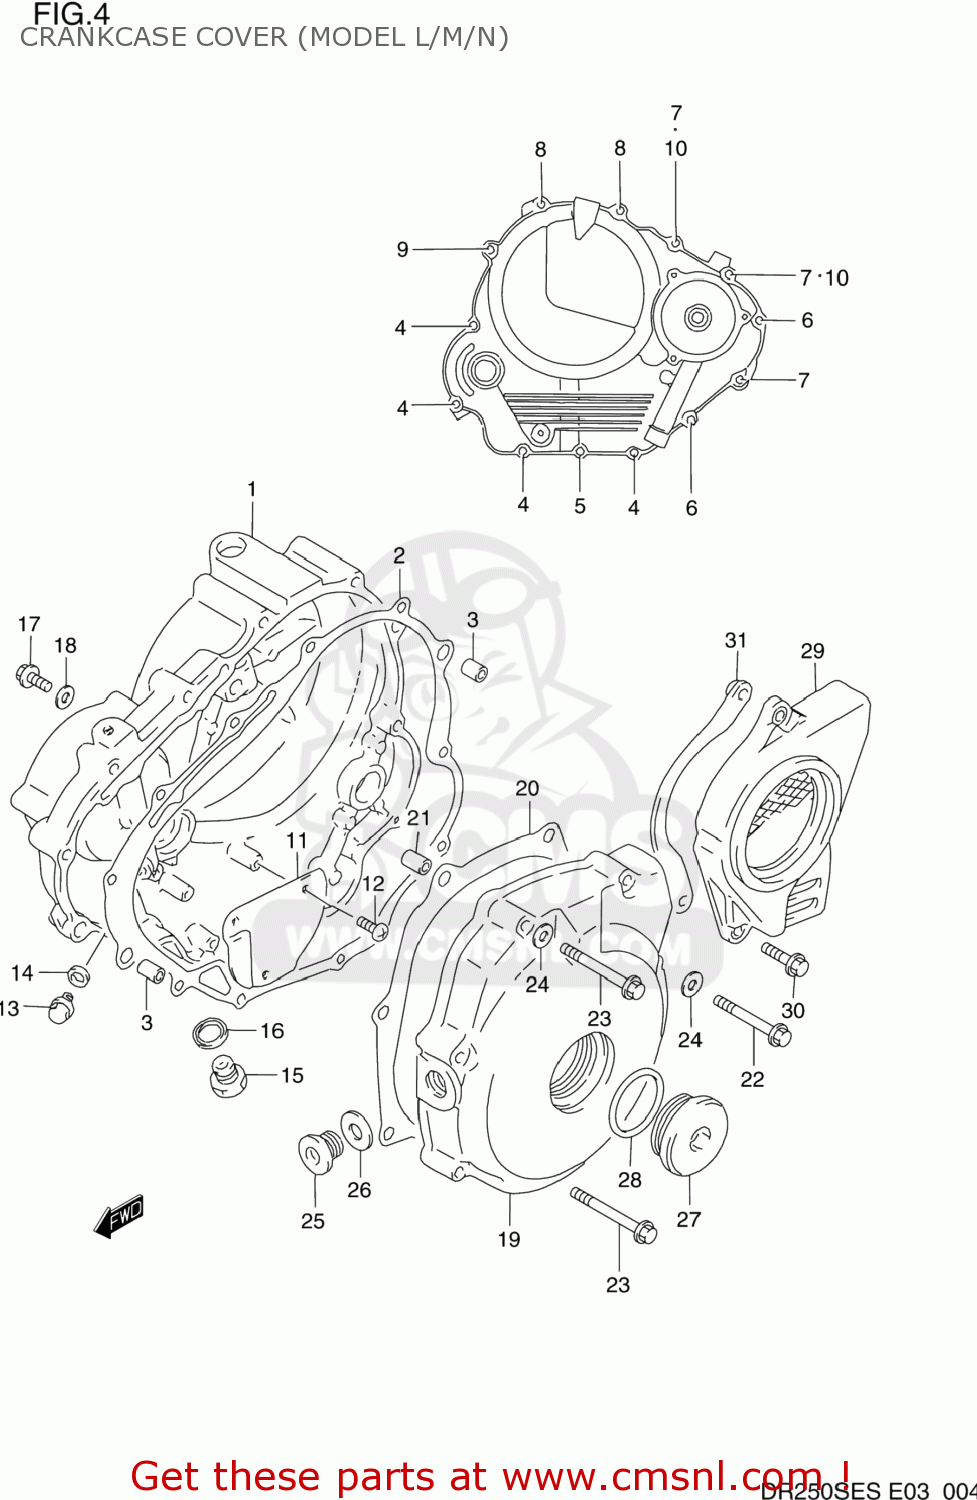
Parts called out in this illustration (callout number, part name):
1	COVER,CLUTCH
2	GASKET,CLUTCH COVER (NAS)
3	PIN
4	BOLT
5	BOLT
6	BOLT
7	BOLT
8	BOLT
9	BOLT
10	GASKET(5.8X13X1.2) (NAS)
11	SEPARATOR,OIL RETURN
12	SCREW(5X10)
13	BOLT(6X8)
14	GASKET(6.2X11X1).2 (NAS)
15	PLUG,14X12
16	GASKET(14X19.2X2) (NAS)
17	SCREW (6X10)
18	GASKET(5.8X13X1.2) (NAS)
19	COVER,MAGNETO
20	GASKET,MAGNETO COVER (NAS)
21	PIN
22	BOLT
23	BOLT
24	GASKET(5.8X13X1.2) (NAS)
25	PLUG,14X12
26	GASKET(14X19.2X2) (NAS)
27	PLUG(SILVER)
28	O RING(D:3.1,ID:32.7)
29	COVER,ENGINE SPROCKET
30	BOLT
31	PLATE,FR CHAIN GUIDE
